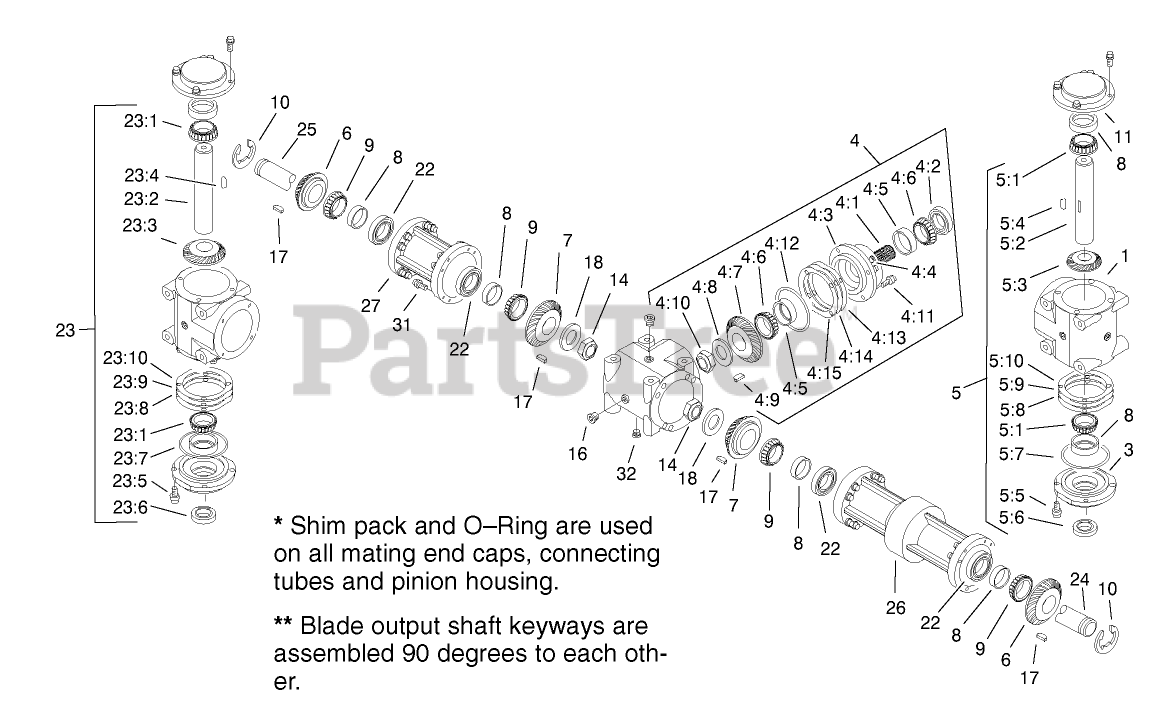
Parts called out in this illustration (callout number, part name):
3	CAP-END, OPEN
4	SPLINED PINION ASM
4:1	SHAFT - INPUT, SPLINED
4:3	HOUSING - PINION
4:5	Bearing-Cup
4:6	Bearing-Cone
4:7	GEAR - 27 TOOTH
4:8	WASHER
4:9	KEY-WOODRUFF
4:10	NUT-JAM
4:12	O-RING
4:13	SHIM-BROWN, .010IN
4:14	SHIM-BLUE, .005IN
4:15	SHIM-GREEN, .003IN
5	LH SHAFT ASM
5:1	Bearing-Cone
5:2	SHAFT - CROSS, A/D
5:3	GEAR - 29 TOOTH
5:4	KEY-WOODRUFF
5:6	SEAL
5:7	O-RING
5:8	SHIM-BROWN, .010IN
5:9	SHIM-BLUE, .005IN
5:10	SHIM-GREEN, .003IN
6	GEAR - 27 TOOTH
7	GEAR - 29 TOOTH
8	Bearing-Cup
9	Bearing-Cone
10	CLIP-RETAINING
11	CAP-END, CLOSED
14	NUT-JAM
17	KEY-WOODRUFF
18	WASHER
23	RH Shaft ASM
23:1	Bearing-Cone
23:2	SHAFT - CROSS, B/D
23:3	GEAR - 29 TOOTH
23:4	KEY-WOODRUFF
23:6	SEAL
23:7	O-RING
23:8	SHIM-BROWN, .010IN
23:9	SHIM-BLUE, .005IN
23:10	SHIM-GREEN, .003IN
24	SHAFT - CONNECTING, LONG
25	SHAFT - CONNECTING, SHORT
26	FLANGE - CONNECTING, LONG
27	FLANGE - CONNECTING, SHORT
32	PLUG-MAGNETIC
